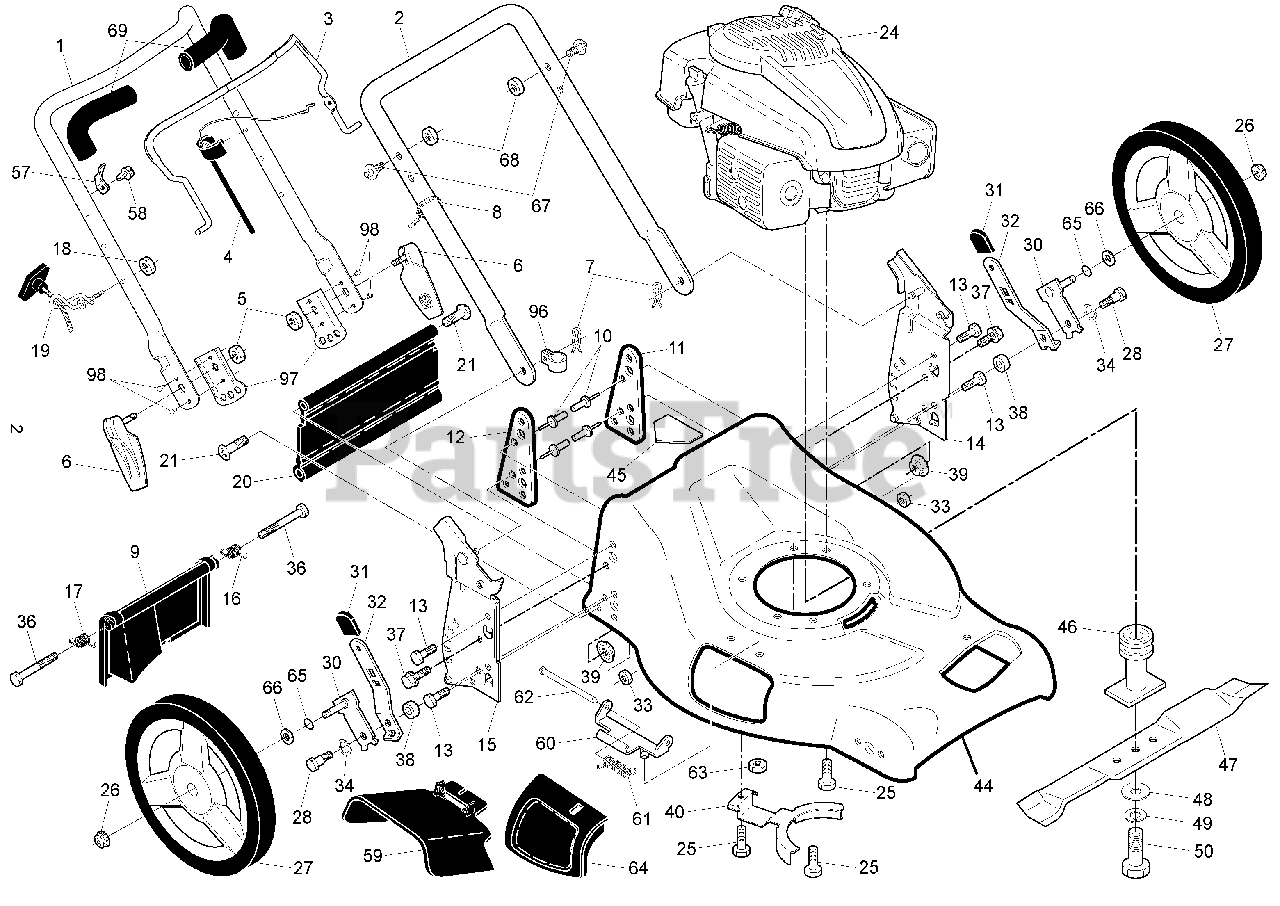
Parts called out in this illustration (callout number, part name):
1	Upper Handle
2	Lower Handle
3	Control Bar
4	Engine Zone Control Cable
5	Locknut, Hex 1/4-20
6	Handle Knob Assembly, Quick-Release
7	Hairpin Cotter
8	Wire Tie
9	Rear Door Assembly
11	Support Bracket, LH
12	Support Bracket, RH
13	Screw 1/4-20 x 5/8
14	Handle Bracket Assembly, LH
15	Handle Bracket Assembly, RH
16	Spring, Rear Door, LH
17	Spring, Rear Door, RH
18	Locknut, Hex 1/4-20
19	Rope Guide
20	Rear Skirt
21	Screw, Hinge
25	Hex Head Thread Rolling Screw 3/8-16 x 1-1/8
26	Hex Flange Nut
27	Wheel & Tire Assembly, Rear, 12"
28	Shoulder Bolt 5/16-18 x .33
30	Axle Arm Assembly, Rear
31	Selector Knob
32	Selector Spring
33	Nut, Hex 5/16-18
34	Washer, Curved, Cylindrical
37	Thread Cutting Screw w/Sems 5/16-18 x 3/4
39	Nut, Hex, Flanged 5/16-18
40	Belt Keeper
44	Lawn Mower Housing
45	Danger Decal
46	Blade Adapter / Pulley
47	Blade 21"
48	Hardened Washer
49	Helical Washer 3/8-24 x 1-3/8 Grade 8
50	Hex Head Machine Screw 3/8-24 x 1-3/8 Grade 8
57	Upstop Bracket
59	Discharge Deflector
60	Hinge Bracket Assembly
61	Spring, Hinge
62	Rod, Hinge
63	Locknut, Hex 1/4-20
64	Mulcher Door
66	Washer, Flat
68	Nut, Hex
69	Grip, Foam
96	Clip, Cable
97	Bracket, Adjuster
